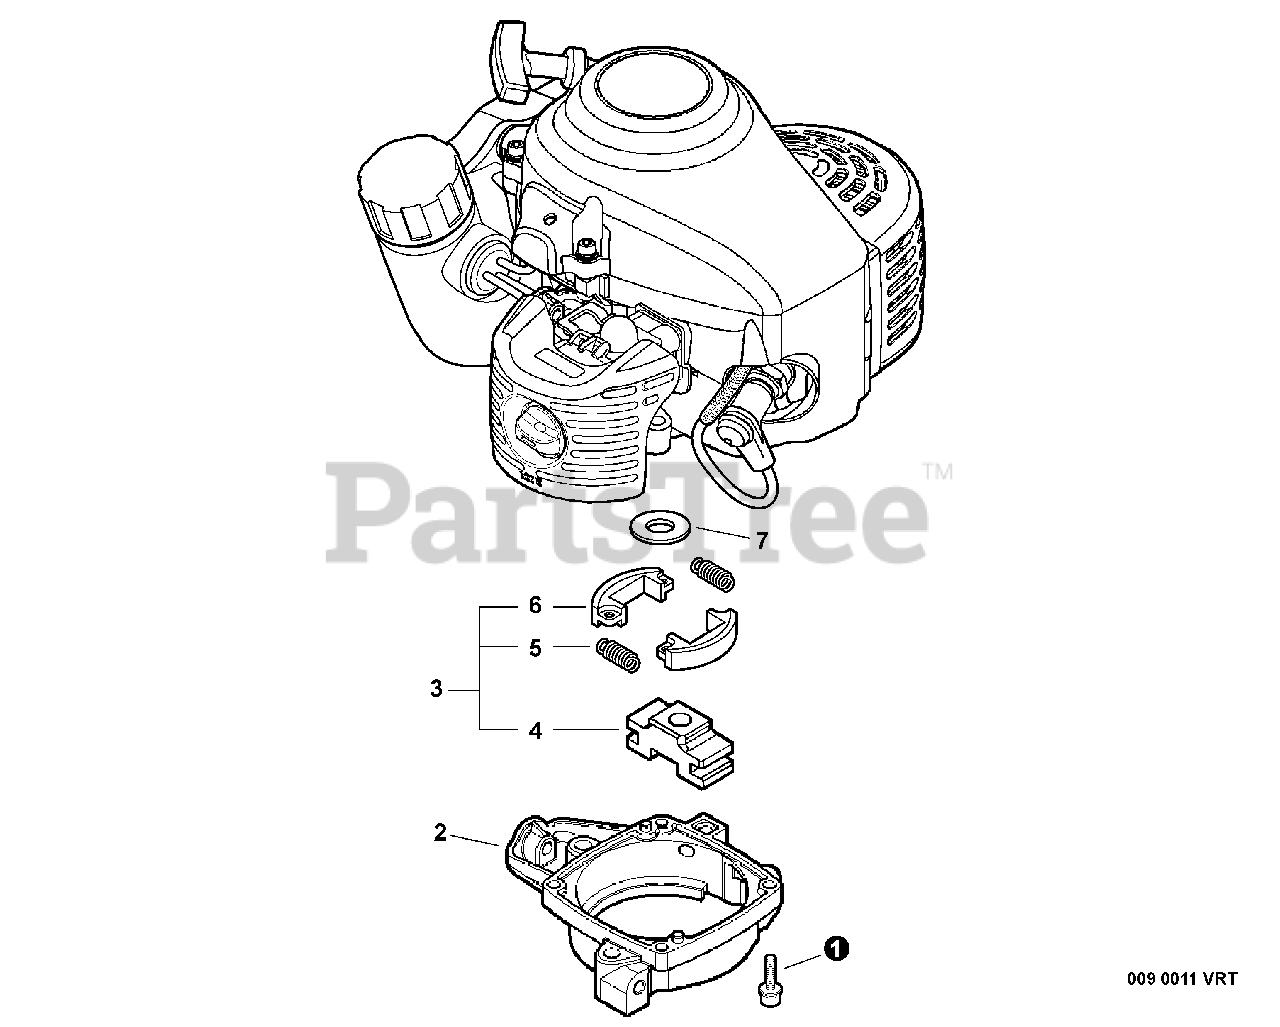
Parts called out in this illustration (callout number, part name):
1	SCREW - 4X16
2	CASE, CLUTCH
3	CLUTCH ASSY
4	HUB, CLUTCH
5	SPRING, CLUTCH
6	SHOE, CLUTCH
7	WASHER - 8
